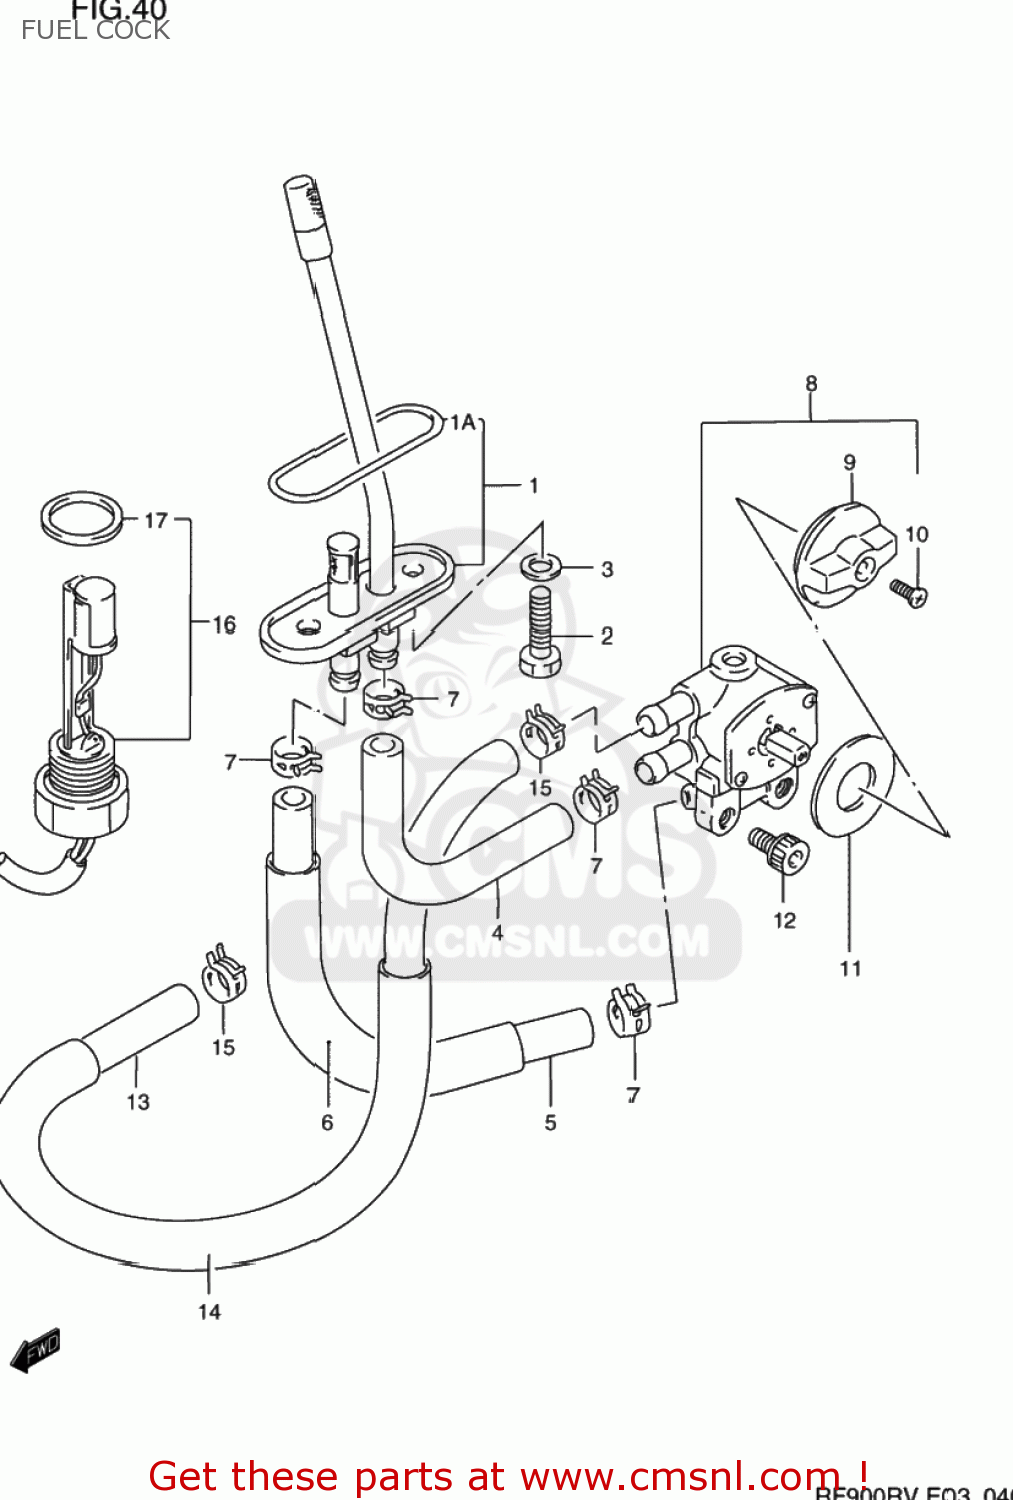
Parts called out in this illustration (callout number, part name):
1	FILTER,FUEL
1A	O RING
2	BOLT(6X20)
3	GASKET(6.4X11.5X0.8) (NAS)
4	HOSE,FUEL ON
5	HOSE(7X12X600)
6	PROTECTOR(14.5X15.5X600)
7	CLIP
8	COCK ASSY,FUEL
9	LEVER,FUEL COCK
10	SCREW,COCK LEVER
11	COVER,FUEL COCK
12	SCREW 6X12
13	HOSE(7X12X600)
14	PROTECTOR(14.5X15.5X600)
15	CLIP
16	GAUGE ASSY,FUEL LEVEL
17	GASKET,FUEL LEVEL GAUGE (NAS)
